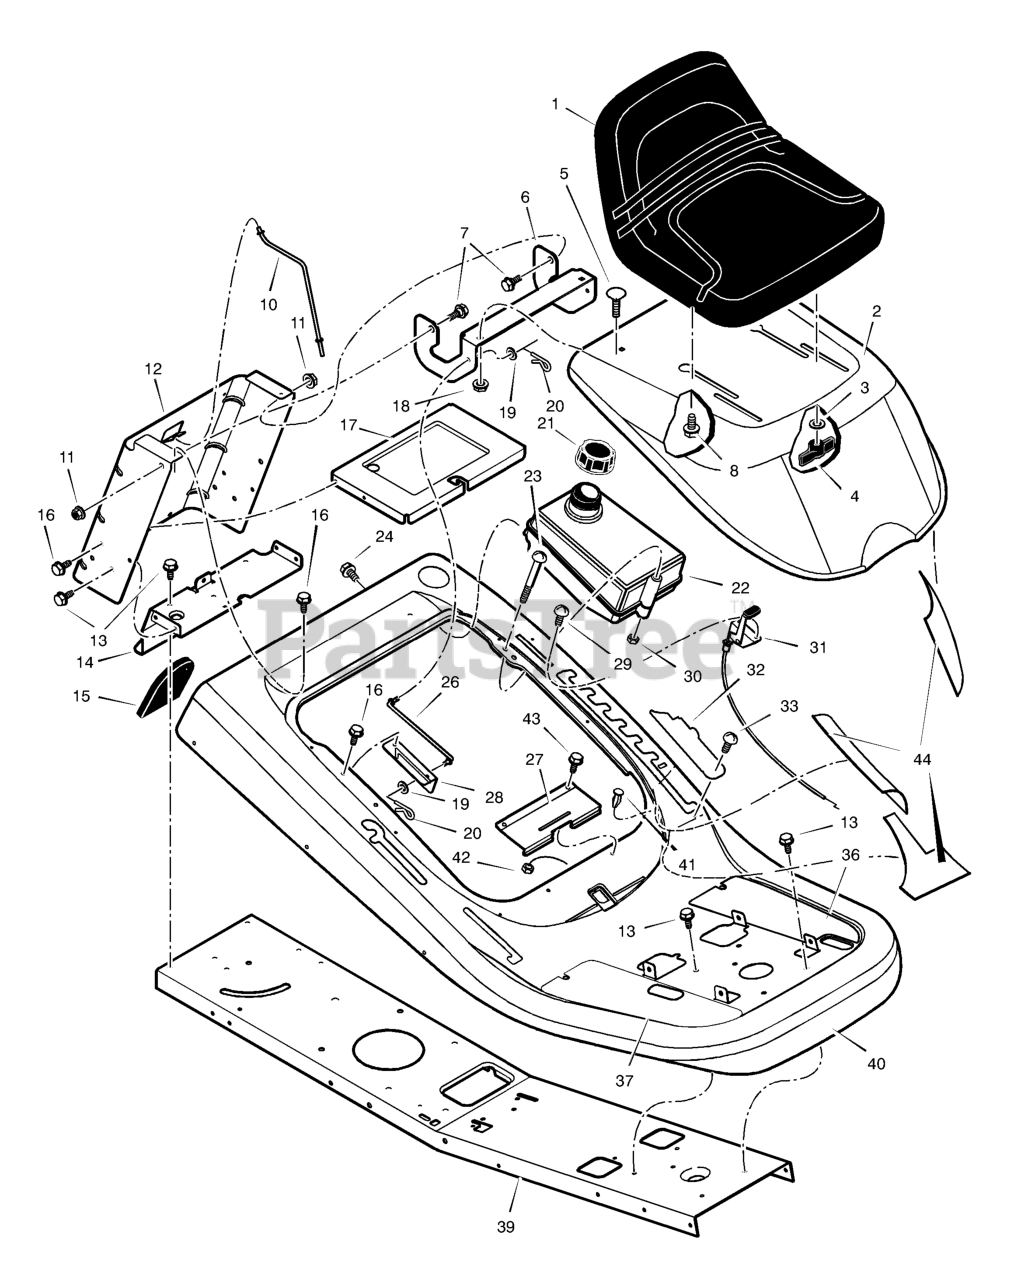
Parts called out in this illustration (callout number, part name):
1	Seat
3	Washer
4	Bolt, Wing
5	Bolt, Carriage
6	Bracket, Hinge
7	Bolt, Shoulder
8	Bolt, Shoulder
10	Rod, Battery
11	Nut, Flange
12	Plate, Rear
14	Plate, Hitch
17	TRAY, Battery
18	Nut, Flange
19	Washer
20	Pin, Cotter
21	Cap, Fuel Tank
22	Tank, Fuel
26	Rod, Hood Prop
27	Spring, Seat Deck
28	Bracket, Prop Rod
30	Nut, NY-Lock
31	Control, Throttle
32	Cover, Detent (Black)
33	Bolt, Shoulder
36	Footmat, Left
37	Footmat, Right
40	Deck, Seat
41	Bumper
42	Nut
43	Screw
44	Kit, Foil Heat Shield
